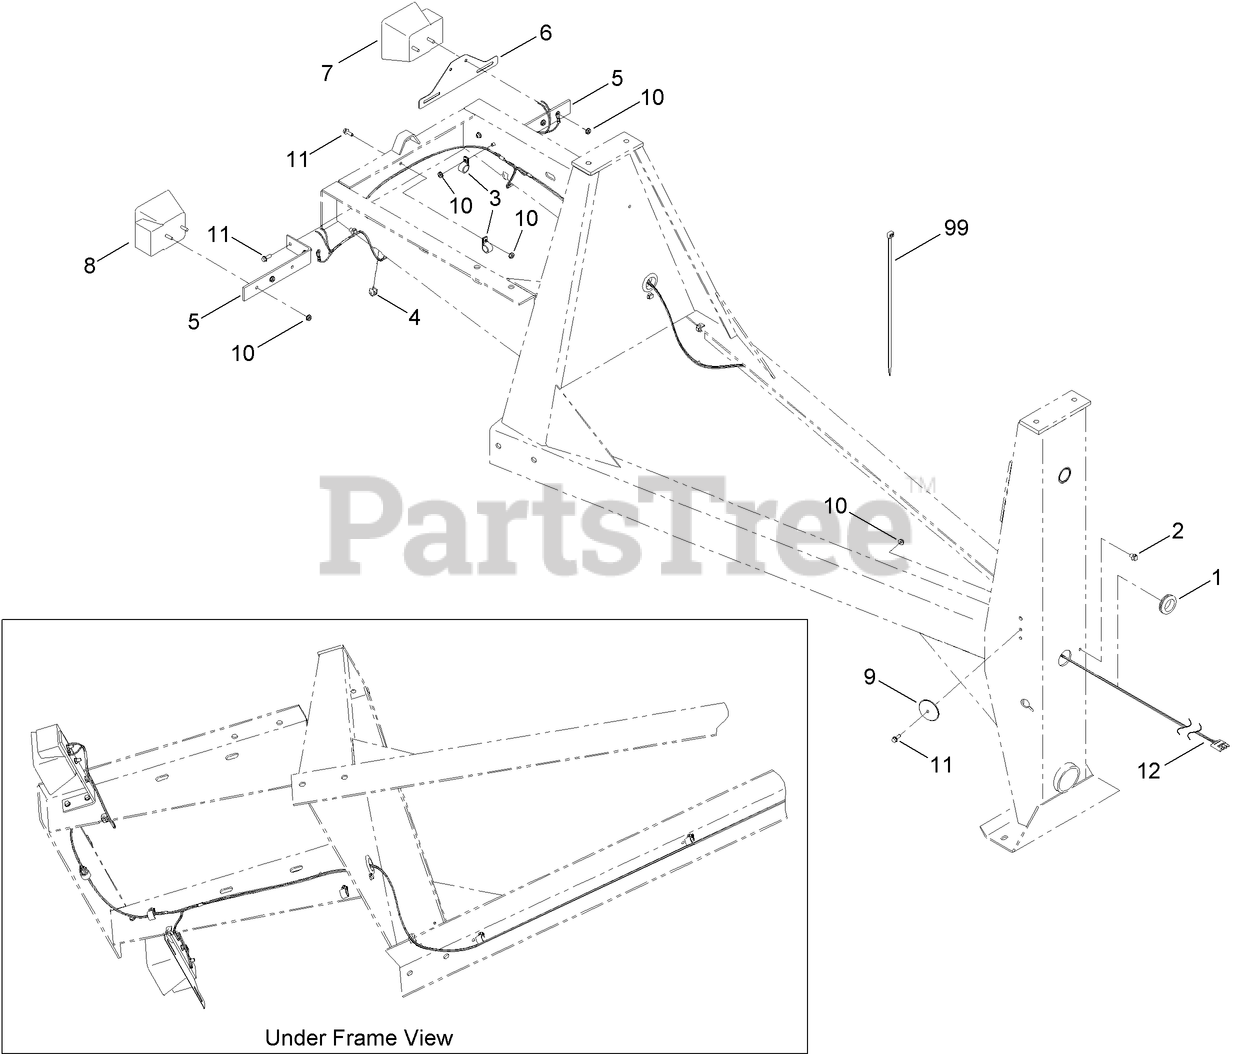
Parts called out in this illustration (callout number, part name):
1	GROMMET
2	CLIP-TIE
3	CLAMP-CABLE
4	CLIP-EDGE
5	BRACKET-UNIVERSAL
6	HOLDER-PLATE, LICENSE
7	LIGHT-TAIL, LH
8	LIGHT-TAIL, RH
9	Reflector-Amber
10	NUT-KEPS
11	SCREW-HHF
12	HARNESS-WIRE, TRAILER LIGHTS
99	TIE-CABLE
